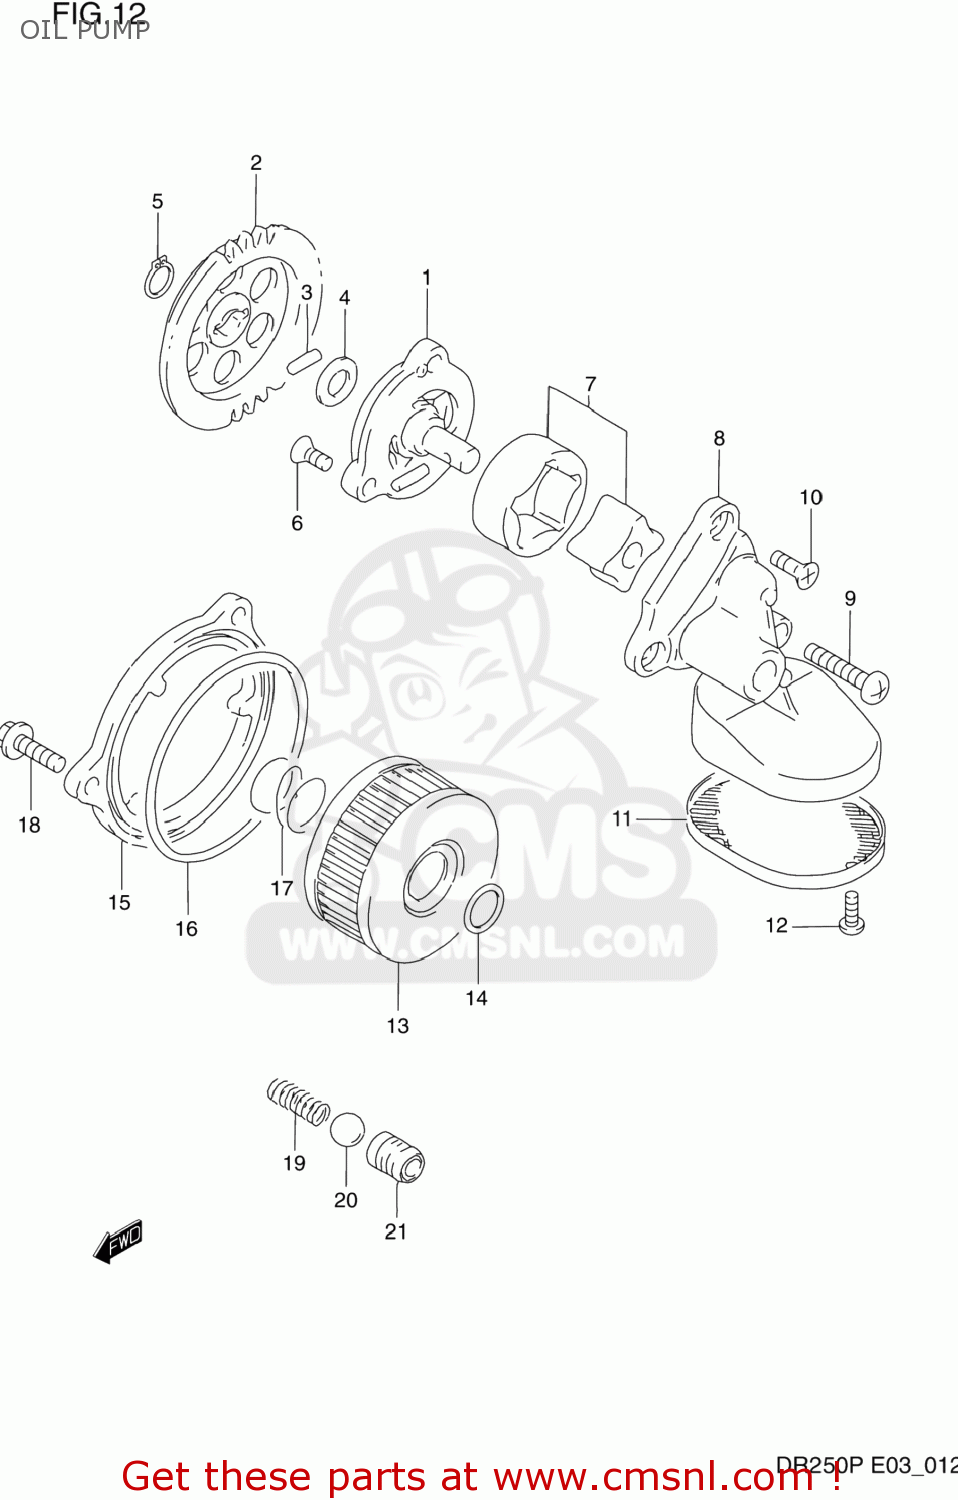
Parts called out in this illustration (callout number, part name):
1	PUMP ASSY,ENGINE OIL NO.1
2	GEAR,OIL PUMP DRIVEN
3	PIN(4X15.8)
4	SHIM
5	CIRCLIP,10MM
6	SCREW M6X1X16
7	ROTOR SET,OIL PUMP,NO.2
8	COVER,OIL PUMP NO.2
9	SCREW,6X30
10	SCREW M6X1X16
11	STRAINER,OIL PUMP NO.2
12	SCREW 5X10
13	FILTER ASSY,ENGINE OIL
14	O RING(D:2.4,ID:15.8)
15	CAP,OIL FILTER
16	O RING(D:2.4,ID:73)
17	SPRING
18	BOLT
19	SPRING
20	BALL
21	SEAT,OIL CHECK VALVE
